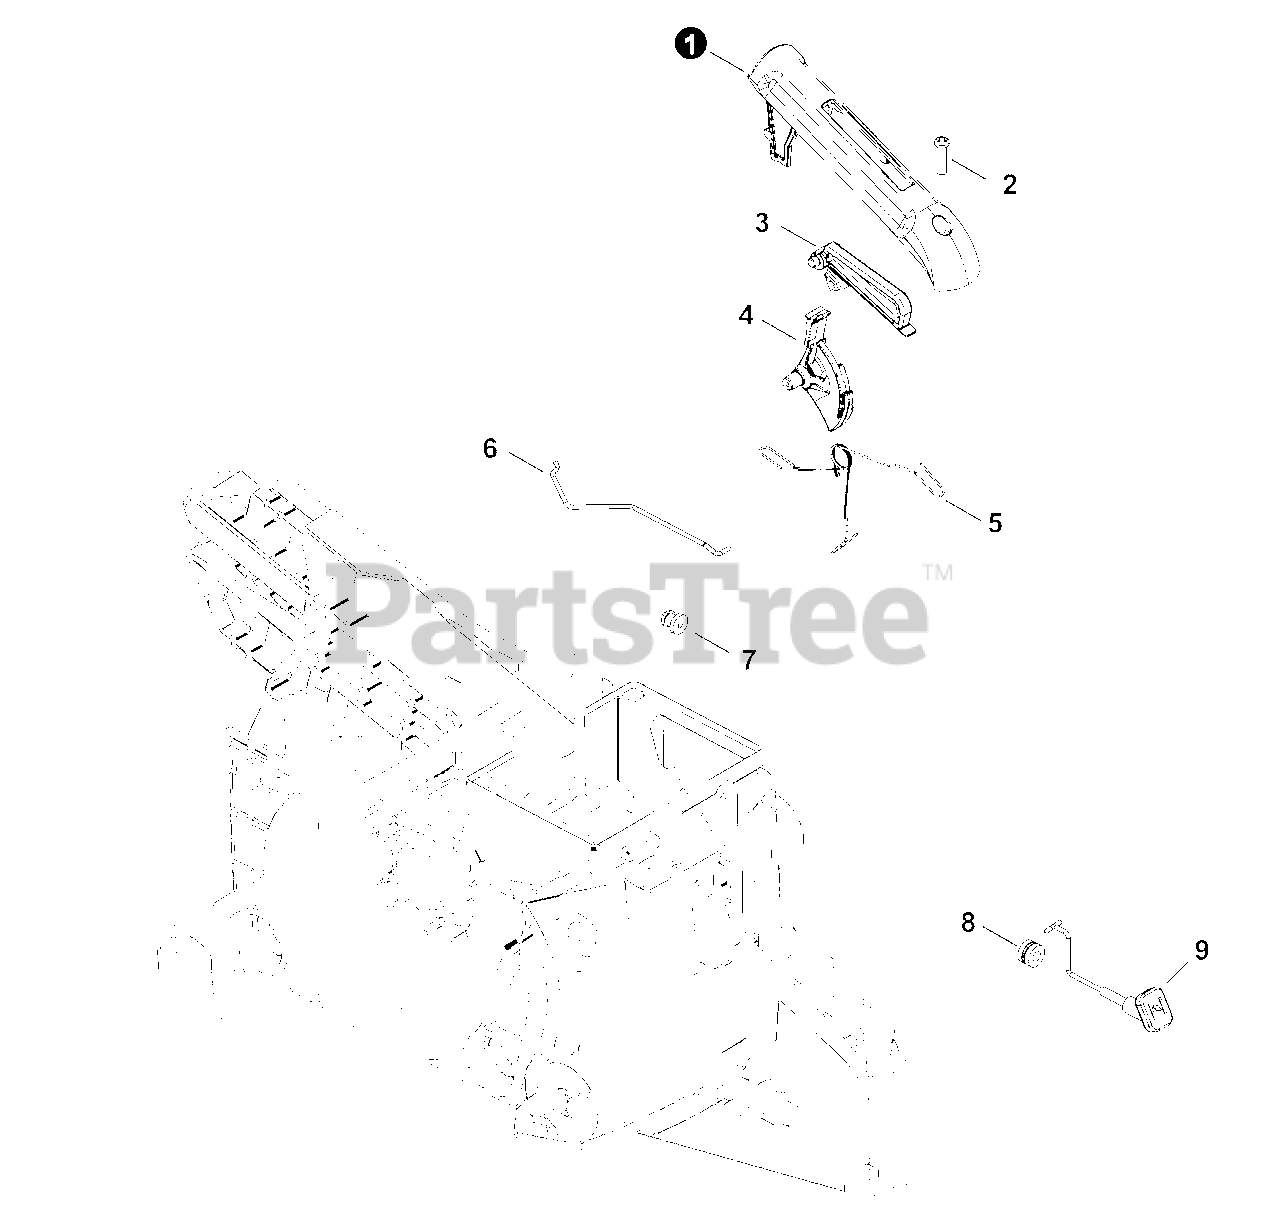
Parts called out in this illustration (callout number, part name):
1	COVER, HANDLE
2	SCREW 4
3	LEVER, THROTTLE LOCKOUT
4	TRIGGER, THROTTLE
5	SPRING, TORSION
6	ROD, THROTTLE
7	GROMMET
8	GROMMET, CHOKE
9	ROD, CHOKE
